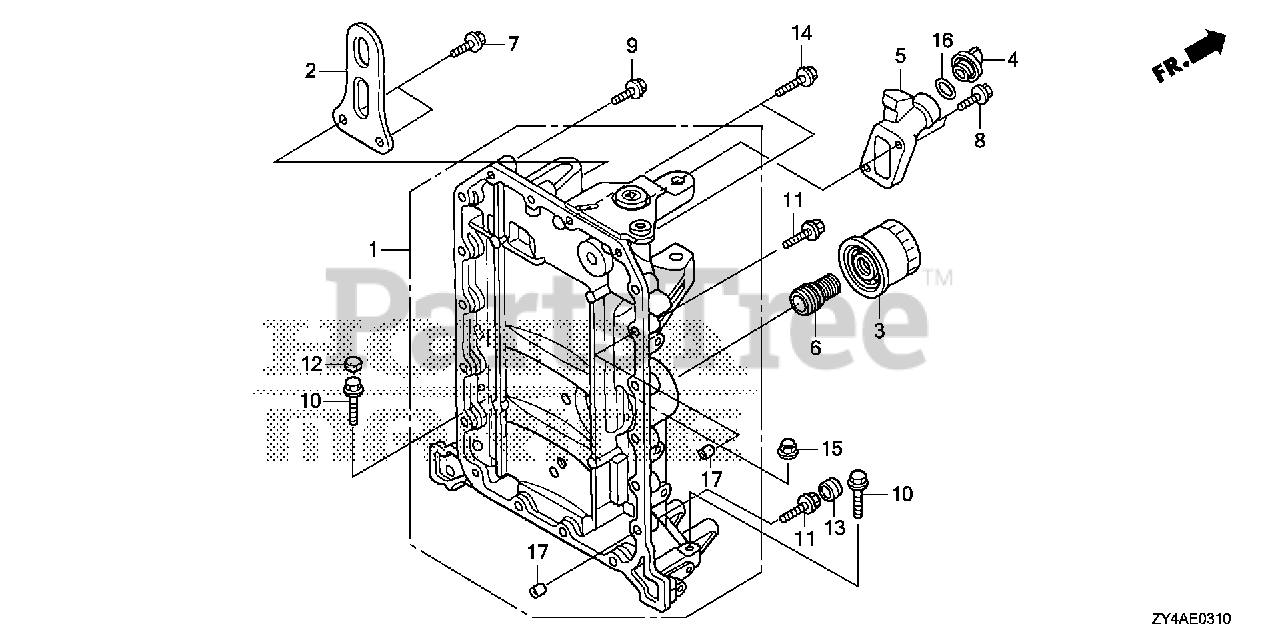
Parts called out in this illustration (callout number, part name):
2	HANGER, ENGINE
3	FILTER, OIL (FILTECH TOYO ROKI) (SOLD IN MULTIPLES OF 30)
3	FILTER, OIL (FILTECH TOYO ROKI) (SOLD INDIVIDUALLY)
4	CAP, OIL (YELLOW)
5	EXTENSION, OIL FILLER
6	HOLDER, OIL FILTER
7	BOLT, FLANGE (8X20)
8	BOLT, FLANGE (6X22)
9	BOLT, FLANGE (6X32)
10	BOLT, FLANGE (10X55)
11	BOLT, FLANGE (6X37)
12	CAP, BOLT (10MM)
13	CAP, BOLT (6MM)
14	BOLT, FLANGE (6X55)
15	NUT, FLANGE CAP (10MM)
16	O-RING (26X2.7)
17	PIN, DOWEL (8X14)
